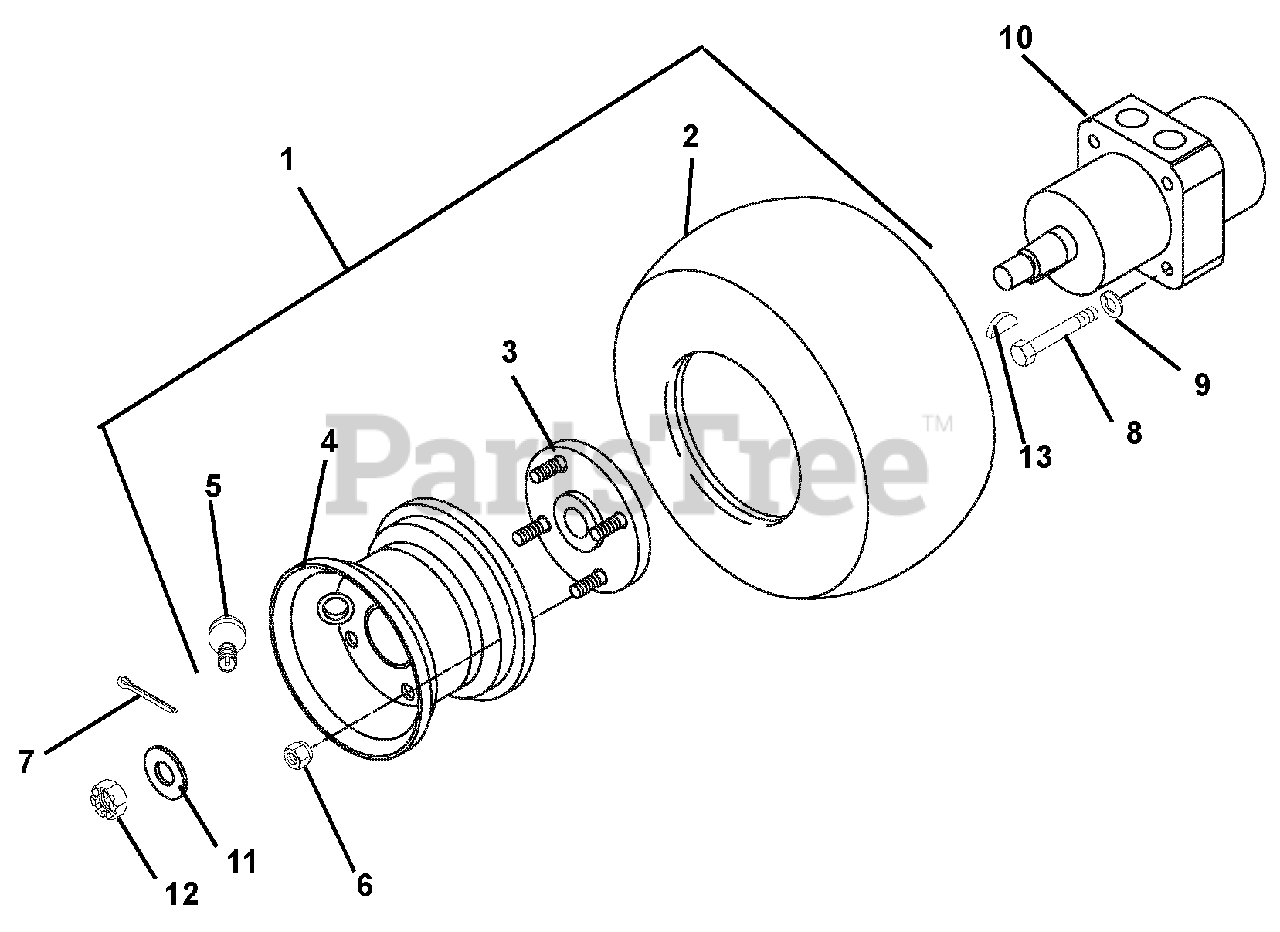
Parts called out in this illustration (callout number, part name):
1	Assembly, Tire and Wheel (includes 2 thru 6)
2	Tire 18 x 8.50 - 8
3	Assembly-Hub
4	Assembly-Rim
5	Valve Stem Assembly
6	Nut-Lug .50-20
7	Pin-Center .12 x 1.25
8	Bolt-Hex .38-16 x 1.00 Grade 5
9	Washer-Locking .38 x .094 Regular
10	Motor, Hydraulic Wheel
11	Washer-Flat-Steel .812 x 1.50 x .135
12	Nut, Hex .75-28 Slotted
13	Key-Woodruff .19 x .75
